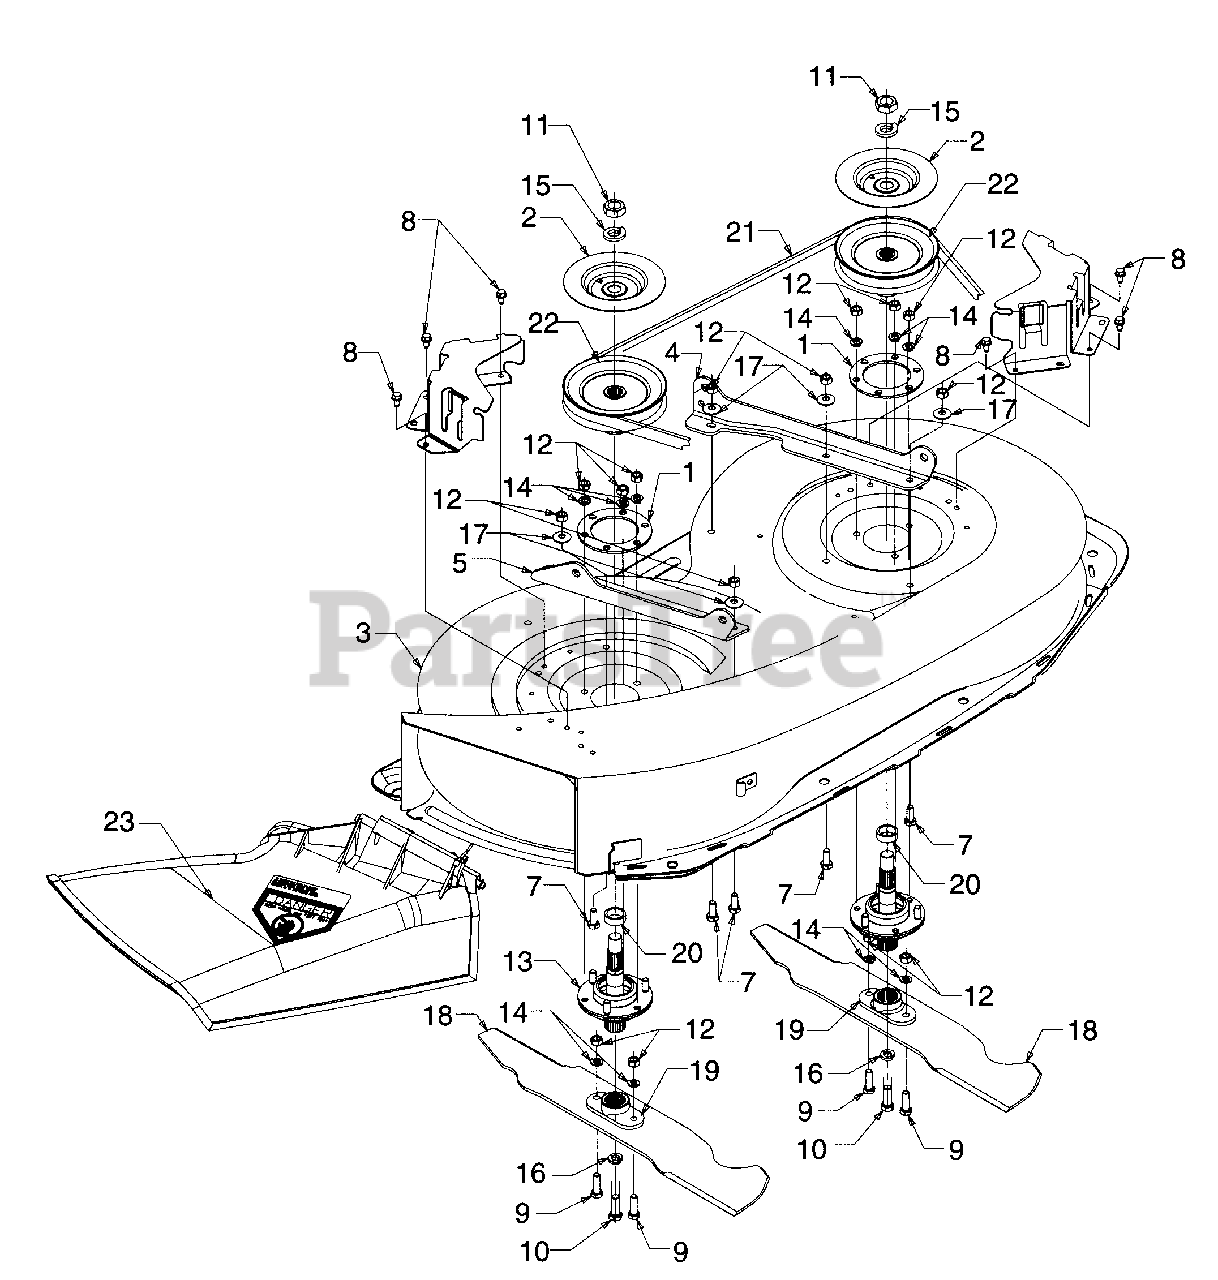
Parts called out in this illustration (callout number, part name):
2	Brake Disc
7	Hex Cap Screw 5/16-24 x .75 Gr. 5
8	Hex Hd. TT Screw 1/4-20 x .50
9	Hex Cap Screw 5/16-24 x 1.00 Gr. 5
10	Hex Screw 3/8-24 x 1.0
11	Hex Jam Nut 5/8-18
12	Hex Nut 5/16-24 Gr.5
13	Blade Spindle Assembly
14	Lock Washer 5/16
15	Lock Washer
16	Lock Washer 3/8
17	Bell Washer .345 I.D. x .88 O.D. x .06
18	High lift blade
19	Blade Adapter
20	Spacer
21	V-Belt
22	Deck Pulley
23	Chute Deflector
